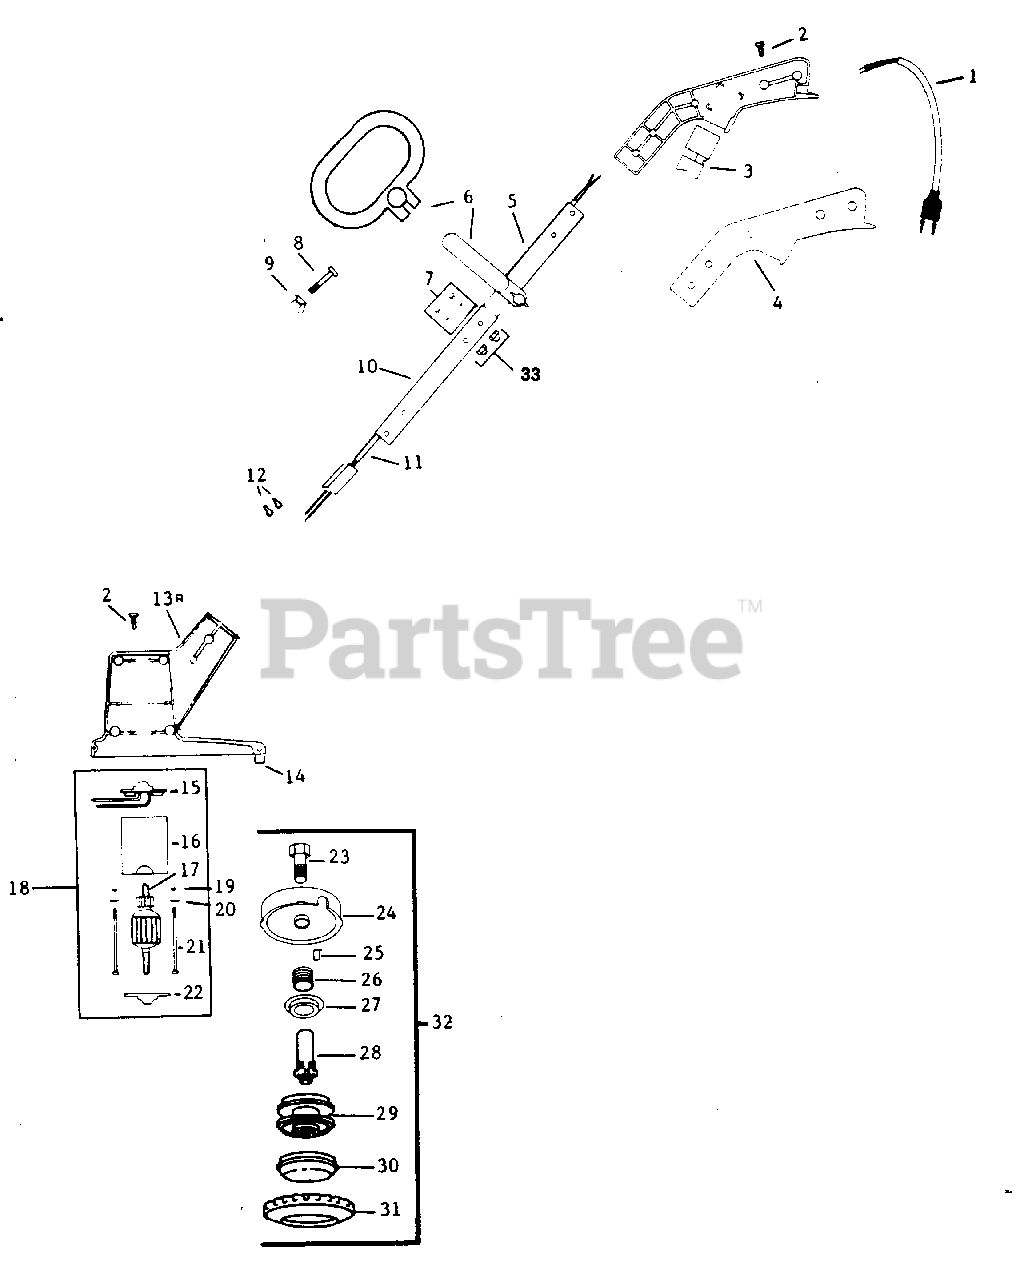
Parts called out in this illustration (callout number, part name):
1	POWER CORD PIGTAIL
4	TRIGGER HANDLE (SET ONLY)
5	UPPER HANDLE TUBE
6	ASSIST HANDLE
9	WING NUT
10	LOWER HANDLE TUBE
11	WIRING HARNESS WITH RECTIFIER
12	CONNECTOR
13	MOTOR HOUSING (SET ONLY)
14	TAIL INTERFERENCE BLADE
15	END BELL w/BRUSHES AND SPRINGS
16	FIELD ASSEMBLY
17	ARMATURE
18	MOTOR (COMPLETE)
20	LOCK WASHER
22	END BELL, OUTPUT
23	DRIVE ADAPTOR
24	HUB w/LINE SAVERS
25	LINE SAVER
26	COIL SPRING
27	COIL SPRING ADAPTOR
28	DRIVE GEAR
29	SPOOL, W/LINE
30	RELEASE BUTTON
32	TAP-N-GO HEAD ASSEMBLY
33	NUT, ACORN
